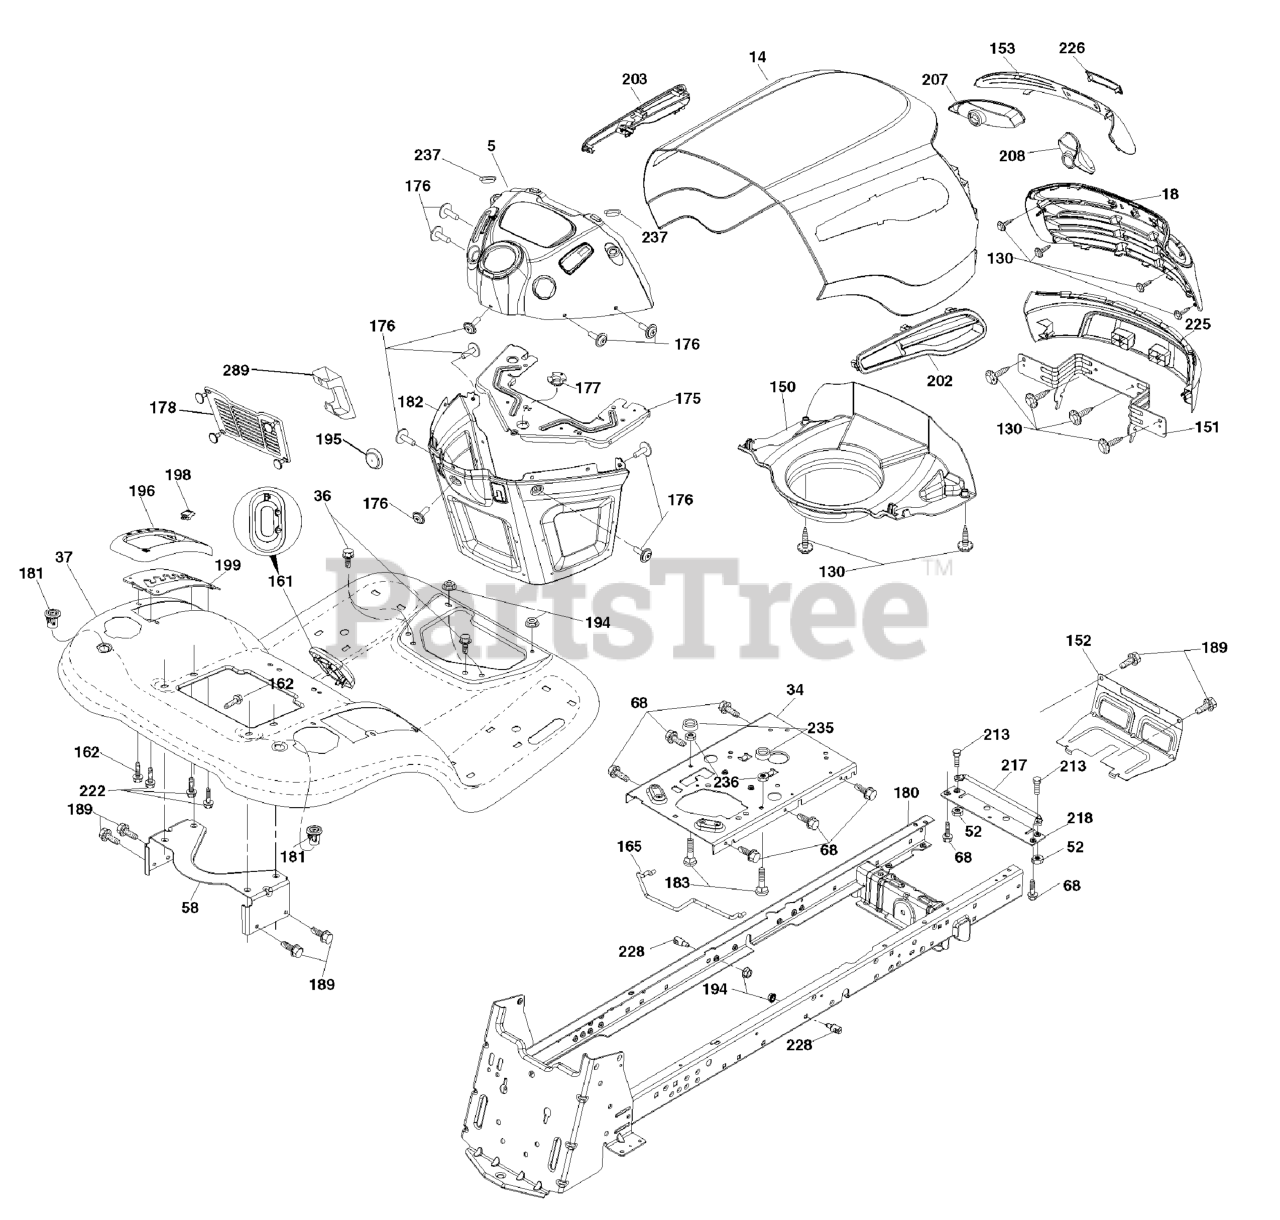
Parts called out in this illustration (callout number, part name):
5	** Dash
14	** Hood
18	** Grille
34	Plate Engine
36	Screw 5/16-18 x 3/4
37	** Fender
52	Nut Crownlock 5/16-18
58	Bracket Support Fender
68	Screw 5/16-18 x 1/2
130	Screw 10 x .750 BOS Thread
150	** Air Duct
151	** Bracket Pivot
152	Shield Browning
153	** Lens Bar
161	Window Fuel
162	Screw
165	Support Tank Rear
175	** Crossmember
176	Screw 10-24 x 5/8
177	Bushing Steering
178	Cargo Asm. Net
180	Chassis
181	Bushing Mtg. Fender Crgo
182	** Dash Lower
183	Bolt 5/16-18 x 1-1/4
189	Screw 5/16-18 x 3/4
194	Nut Lock Hex Flange 5/16-18
195	** Plug Hole Dash
196	** Console Asm. Deck Lift
198	** Indicator Deck Lift
199	Plate Deck Lift
202	** Vent Side Hood RH
203	** Vent Side Hood LH
207	** Bezel LH
208	** Bezel RH
213	Bolt Hex HD 5/16-18 unc x 3/4
217	Rod Pivot Hood
218	X-Piece Hood Stop
222	Screw 1/4-20 x 5/8
225	** Bumper
226	** Logo
228	Stud Fastner
235	Spacer Fender
236	Nut Lock 5/16-18 unc
237	Plug Mount Cargo
289	** Plug Cruise Phone
